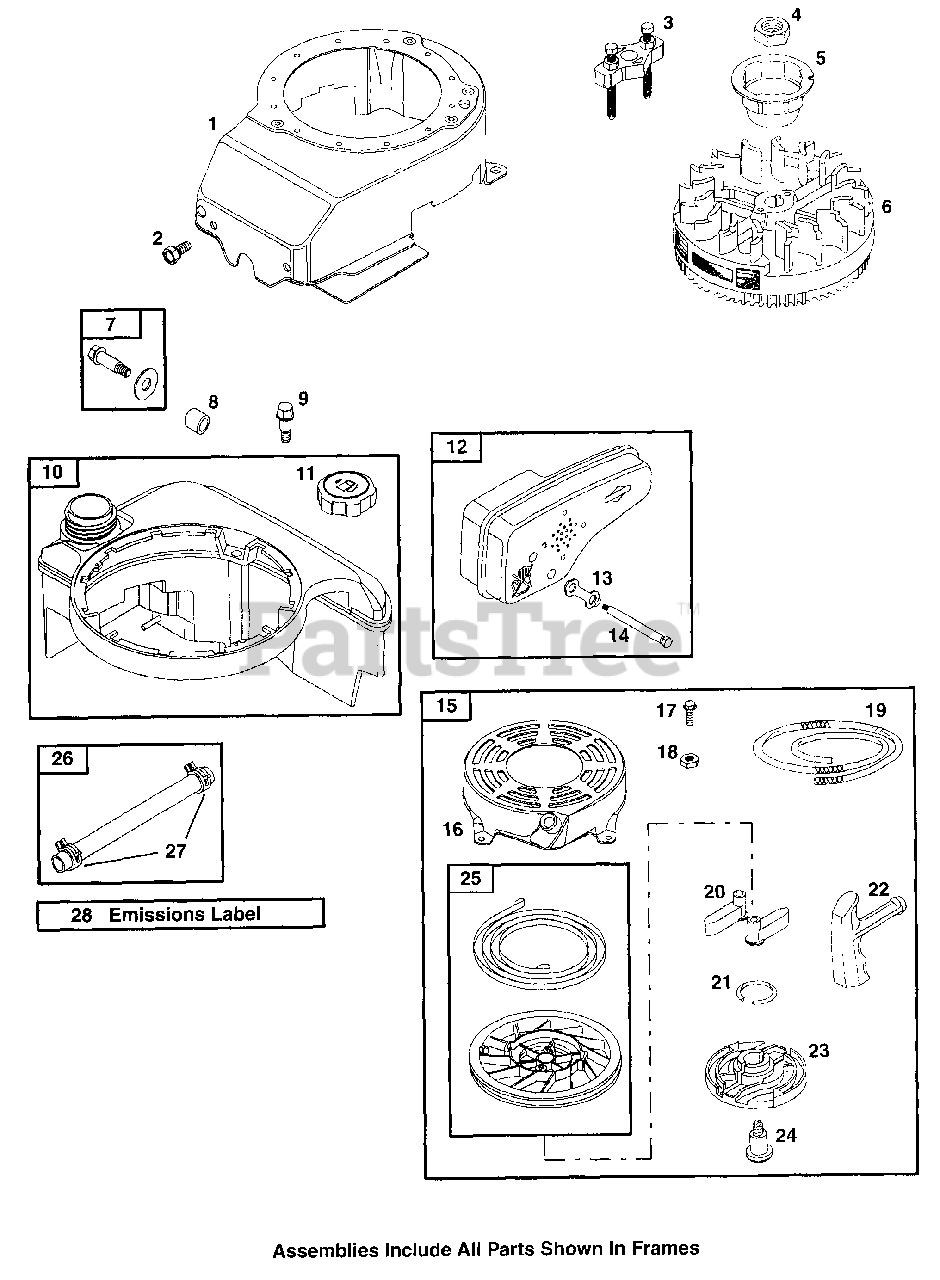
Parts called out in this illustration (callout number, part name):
1	Blower Housing
2	Screw (Blower Housing)
3	Flywheel Puller
4	Nut (Flywheel)
5	Flywheel Cup
6	Flywheel
7	Screw/Washer Kit
8	Fuel Tank Spacer
9	Screw (Fuel Tank)
10	Fuel Tank
11	Fuel Tank Cap
12	Exhaust Muffler
13	Muffler Screw Lock
14	Screw (Exhaust Muffler)
15	Rewind Starter
16	Rewind Starter Housing
17	Screw (Rewind Starter)
18	Nut (Rewind Starter Housing)
19	Starter Rope
20	Ratchet Pawl
21	Friction Spring
22	Starter Rope Grip
23	Pawl Friction Plate
24	Screw (Pawl Friction Plate)
25	Pulley/Spring Assembly
26	Fuel Line
27	Hose Clamp
28	Emissions Label
